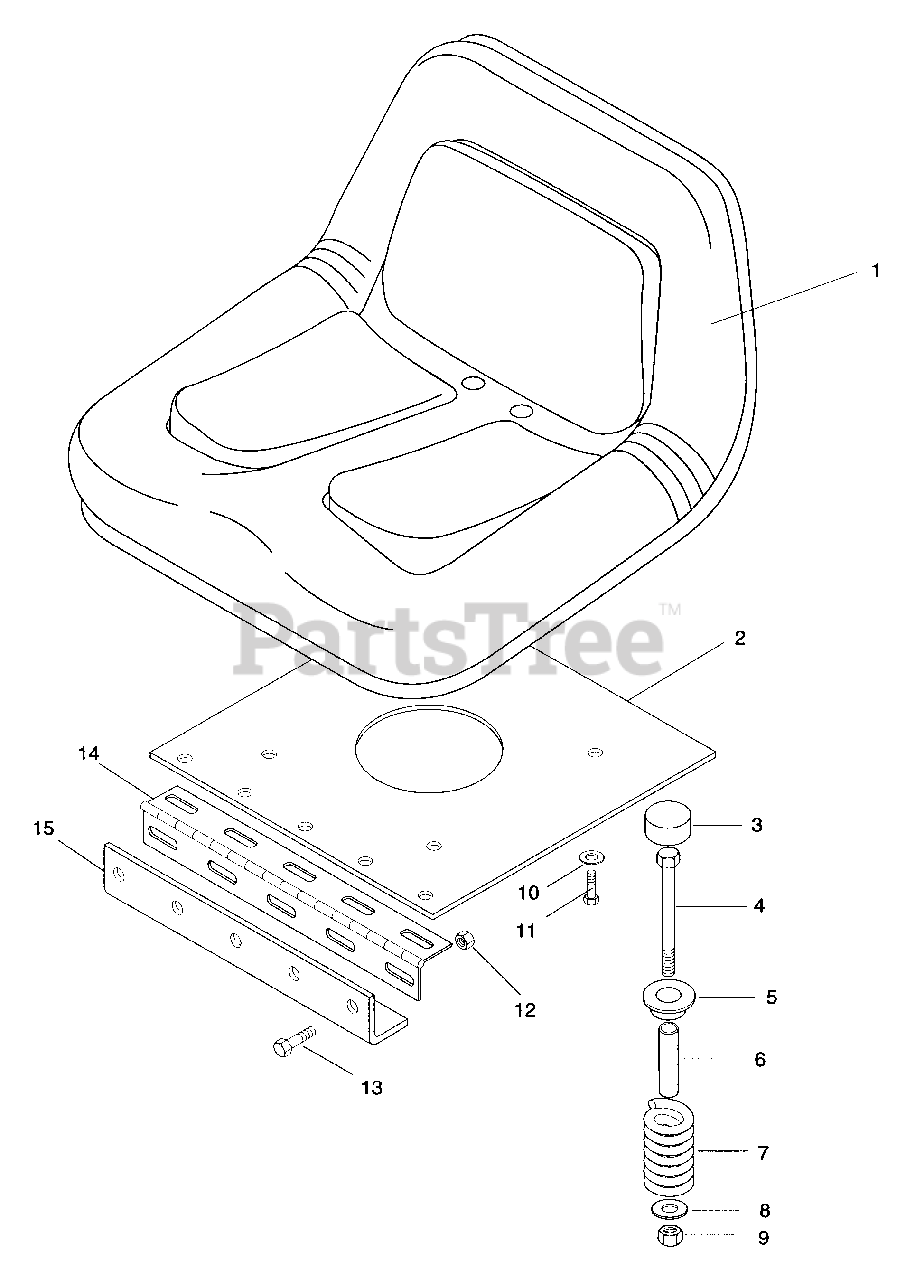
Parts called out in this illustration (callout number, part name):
1	Seat, V-560 High Back
2	Plt, Seat Mtg
3	Molded Cap 1.5 OD, 1.0 ID, .44 THK
4	Blt - Hex .25 - 20 x 2.25
5	Cap, Valve Spring
6	Bushing, Split Rolled
7	Spring, Comp Lee Lhc-148J-O
8	Wshr - Fl - Stl .344 x .688 x .065 Pl
9	Nut - Lk - Nyl .250 - 20 Pl
10	Wshr, Lock .313 x .078 Pl
11	Blt - Hex .31 - 18 x .625 Gr 5
12	Nut - Lk - Nyl .312 - 18 Pl
13	Blt - Hex .31 - 18 x .625 Gr 5
14	Hinge
15	Brkt, Seat Support
